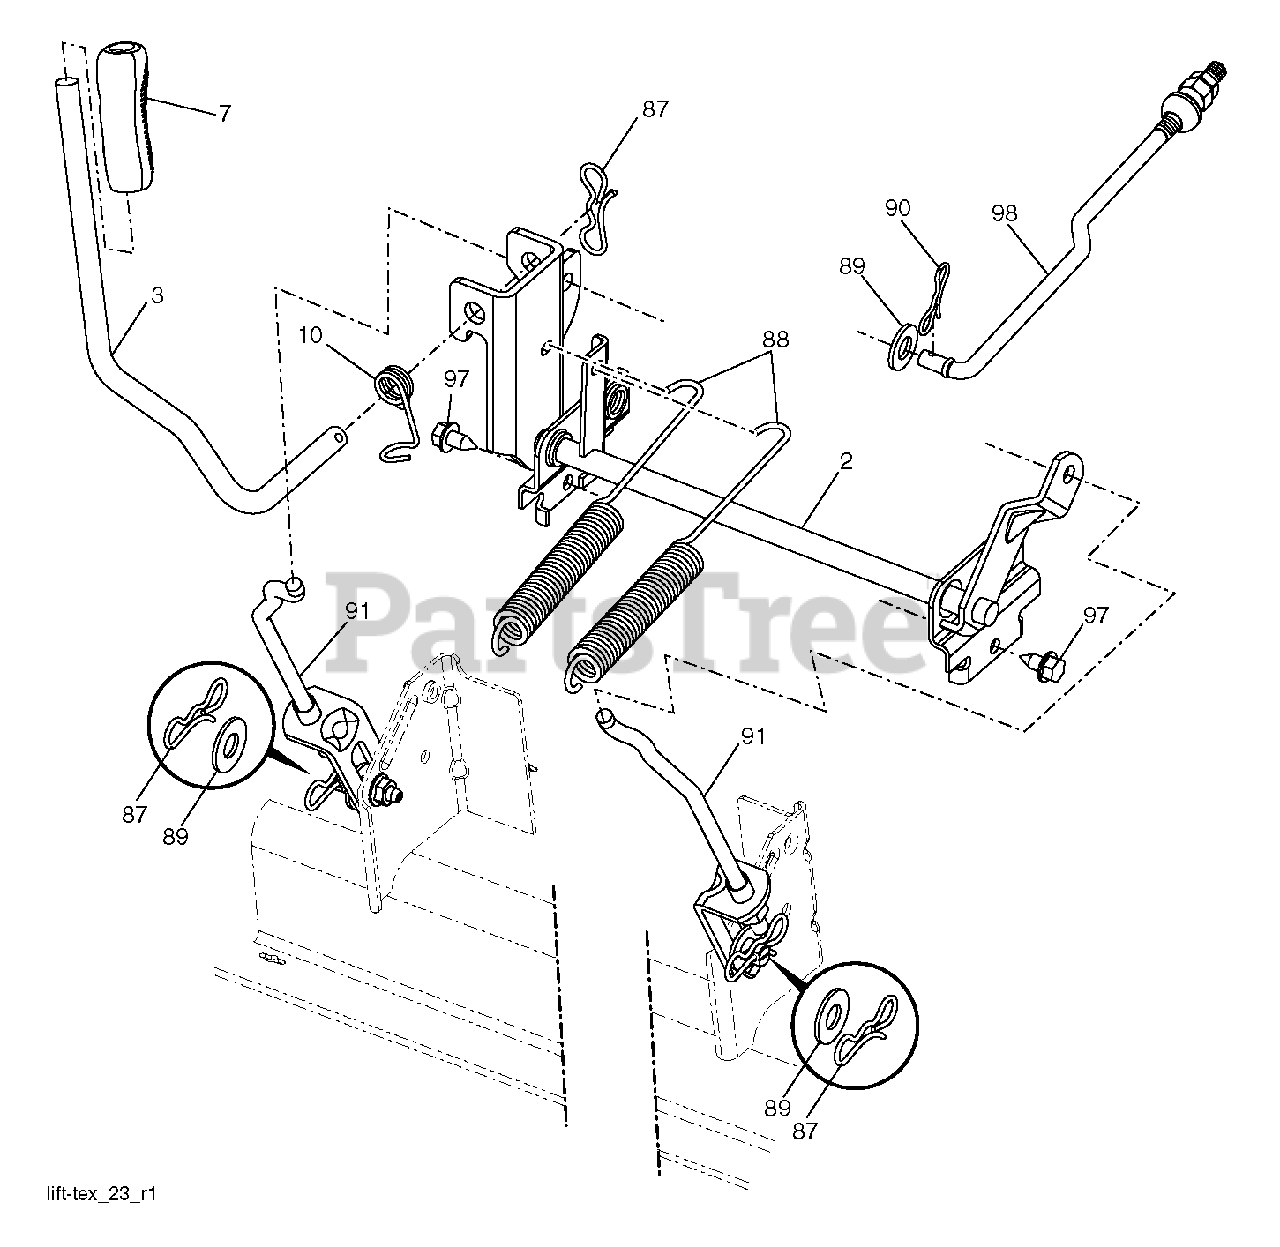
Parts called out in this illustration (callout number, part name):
2	SHAFT.ASM.CROSS.LIFT
3	LEVER.LIFT.HANDLE.GT
7	GRIP.HANDLE.LIFT.PVC.BLACK
10	SPRING.TORSION.LIFT.HANDLE
87	PIN.COTTER.7/16.BOW TI.
88	SPRING.LIFT.ASSIST.GT2
89	WASHER.CLEAR.ZINC
90	PIN.COTTER.5/16.BOW TI
91	LINK.LIFT.ASM.REAR.GT.
97	SCREW, 3/8-16X3/4
98	LINK.ASM.SUSP.FRONT.MWR.10.5
